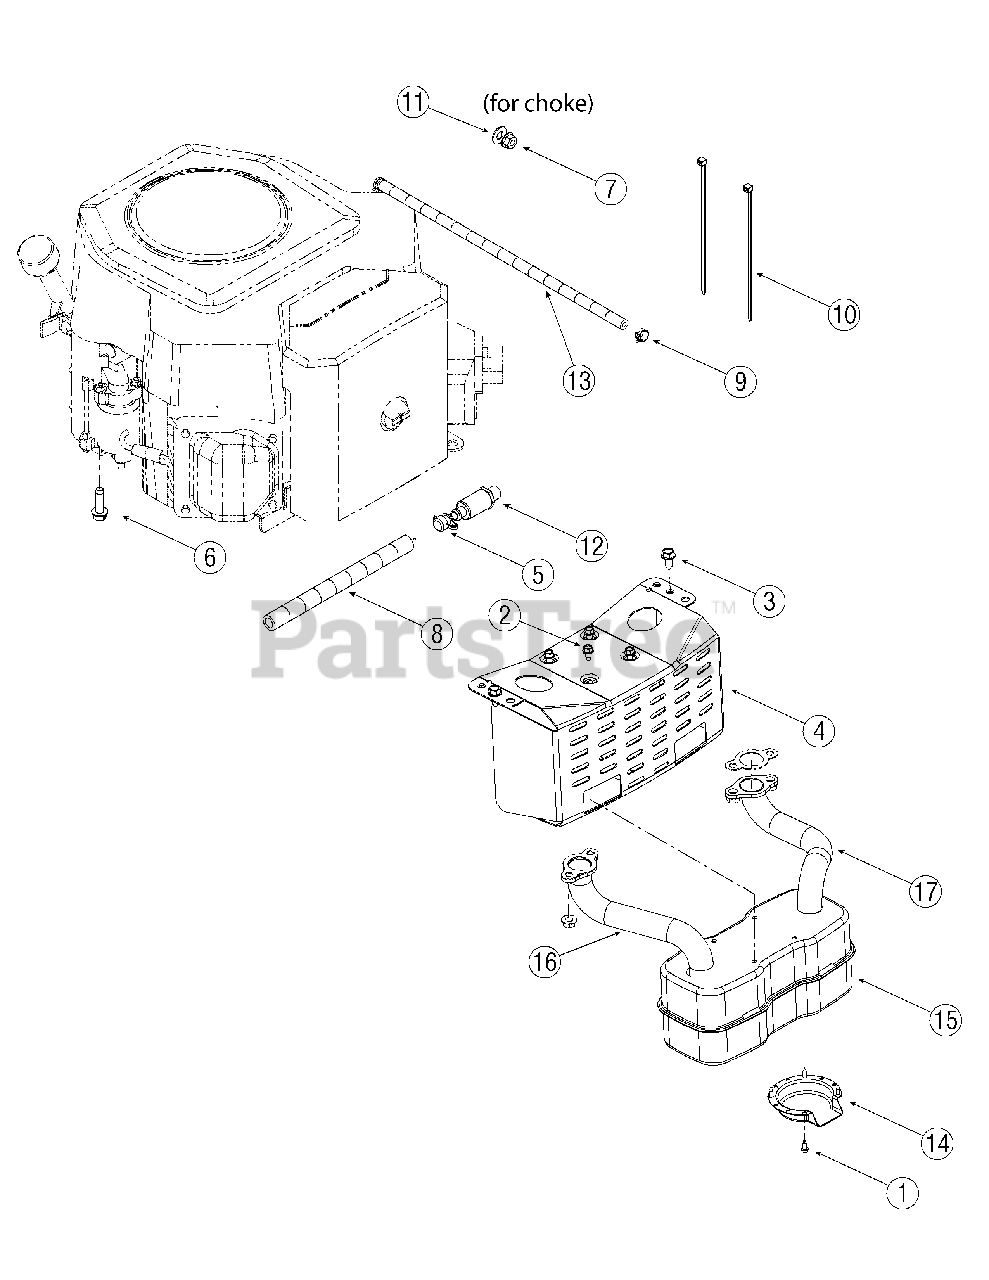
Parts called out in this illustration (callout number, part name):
1	AB Screw #8-18 x 0.5
2	TT Screw 1/4-20 x 0.5
3	AB Screw 5/16-12 x 0.5
5	Oil Drain Cap
6	TT Screw 3/8-16 x 1.25
7	Flange Lock Nut, 3/8-16
8	OIl Drain Extension Hose
11	Lock Washer, .406 x .875
12	Oil Drain Valve
13	Fuel Line Hose
14	Muffler Deflector
15	Muffler
16	Exhaust Pipe - RH
17	Exhaust Pipe - LH
